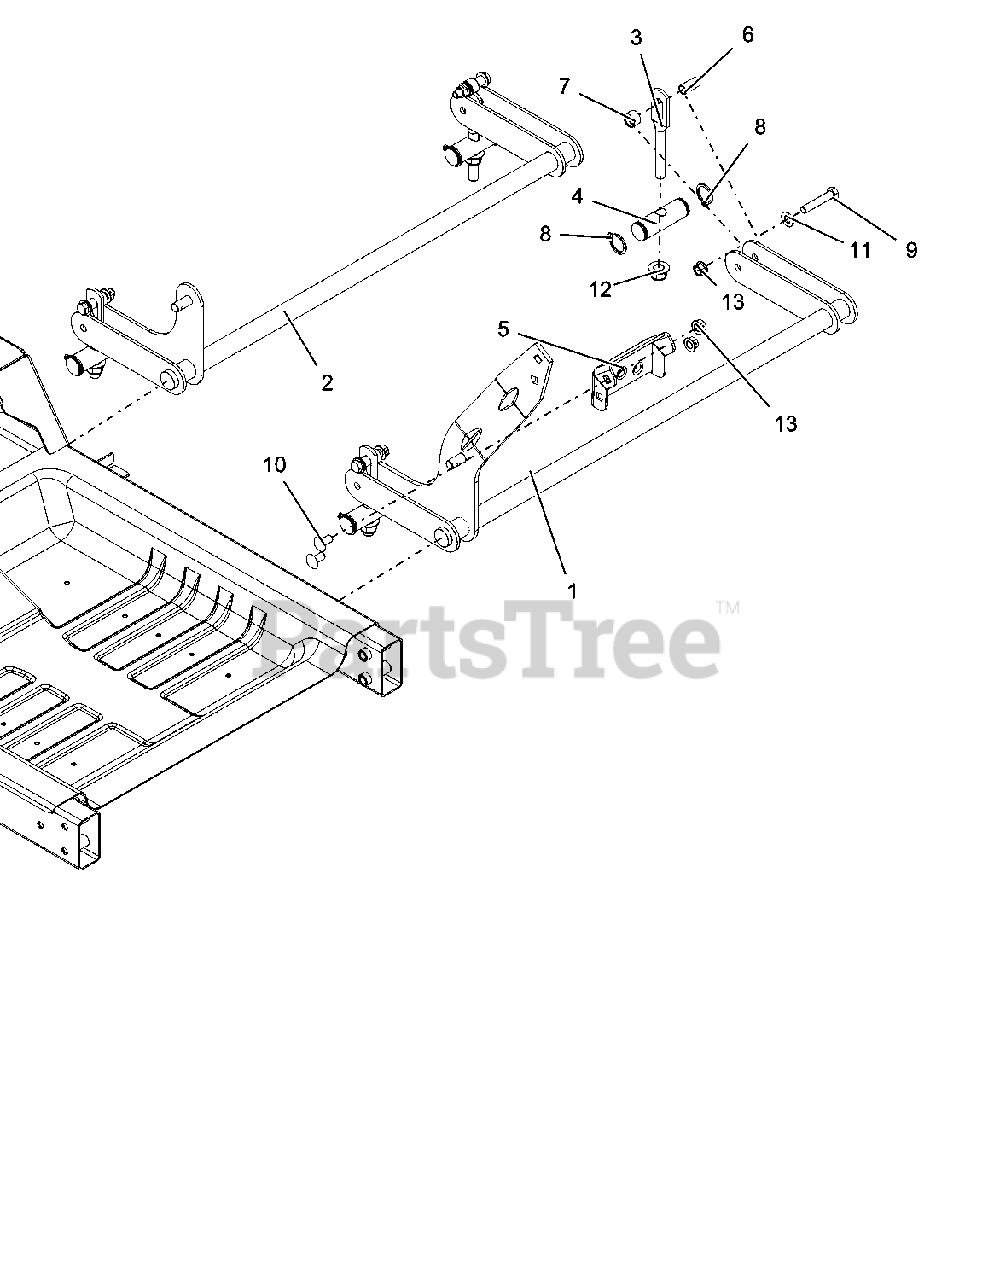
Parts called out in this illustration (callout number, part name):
1	WLDMT, FRONT DECK LIFT PIVOT
2	WLDMT, REAR DECK LIFT PIVOT
3	LINK, DECK
4	SHAFT, DECK LINK PIVOT
5	PEDAL, DECK LIFT (BOLT ON)-BLACK
6	BSHG, SLV .385 X .500 X 1.045
7	BSHG, SLV .510 X .751 X .475
8	RG-RTNG-EXT 1.00X.078
9	BLT-HEX .38-16X2.00 GR8 YWZC
10	BLT-RHDSSQNK .38-16X.75 RIE5230
11	WSHR-FL-STL.406X.812X.065 YWZ
12	NUT-LK-NYL-FLG .50-13 YWZC
13	NUT, LK-CTR-FLG .38-16 YWZC
